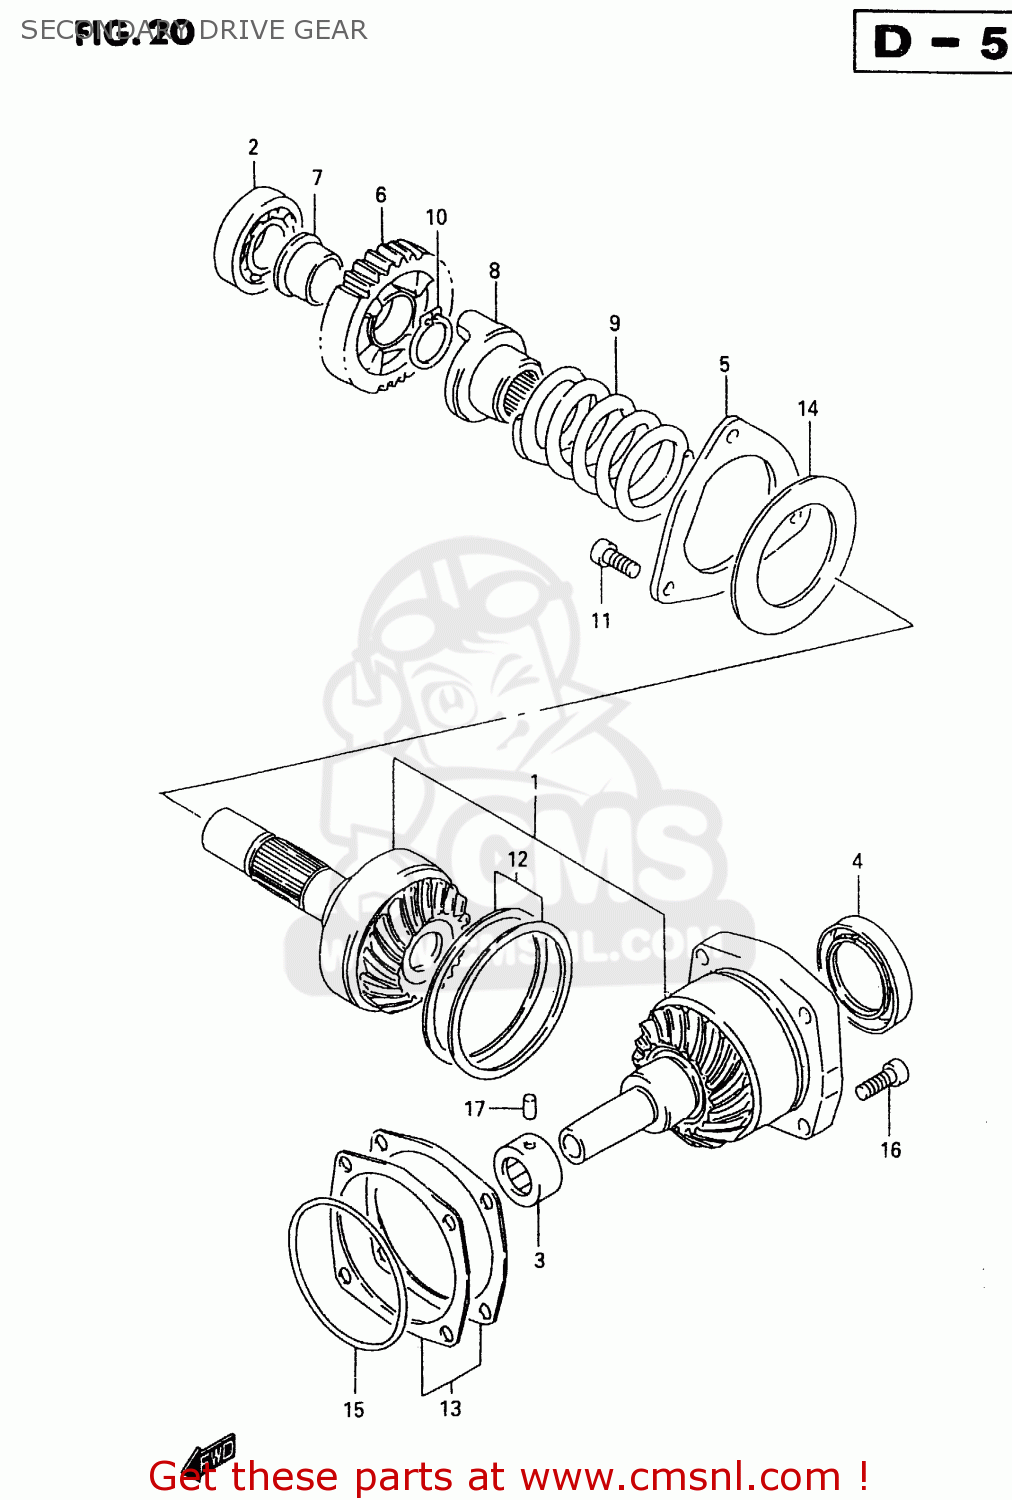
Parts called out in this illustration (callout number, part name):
1	GEAR & HOUSING SET,SECONDARY
2	BEARING(25X62X17)
3	BEARING(20X34X16)
4	SEAL,OIL(44X68X8)
5	STOPPER,SEC DRIVE BEARING
6	GEAR,OVER DRIVING DRIVEN
7	BUSHING,OD DRIVEN GEAR
8	DOG,OUTPUT CAM
9	SPRING
10	CIRCLIP
11	BOLT
12	SHIM SET,SEC DRIVE
13	SHIM SET,SEC DRIVEN
14	WASHER(57X90X3)
15	O RING(D:3.7,ID:76.5)
16	BOLT
17	PIN
